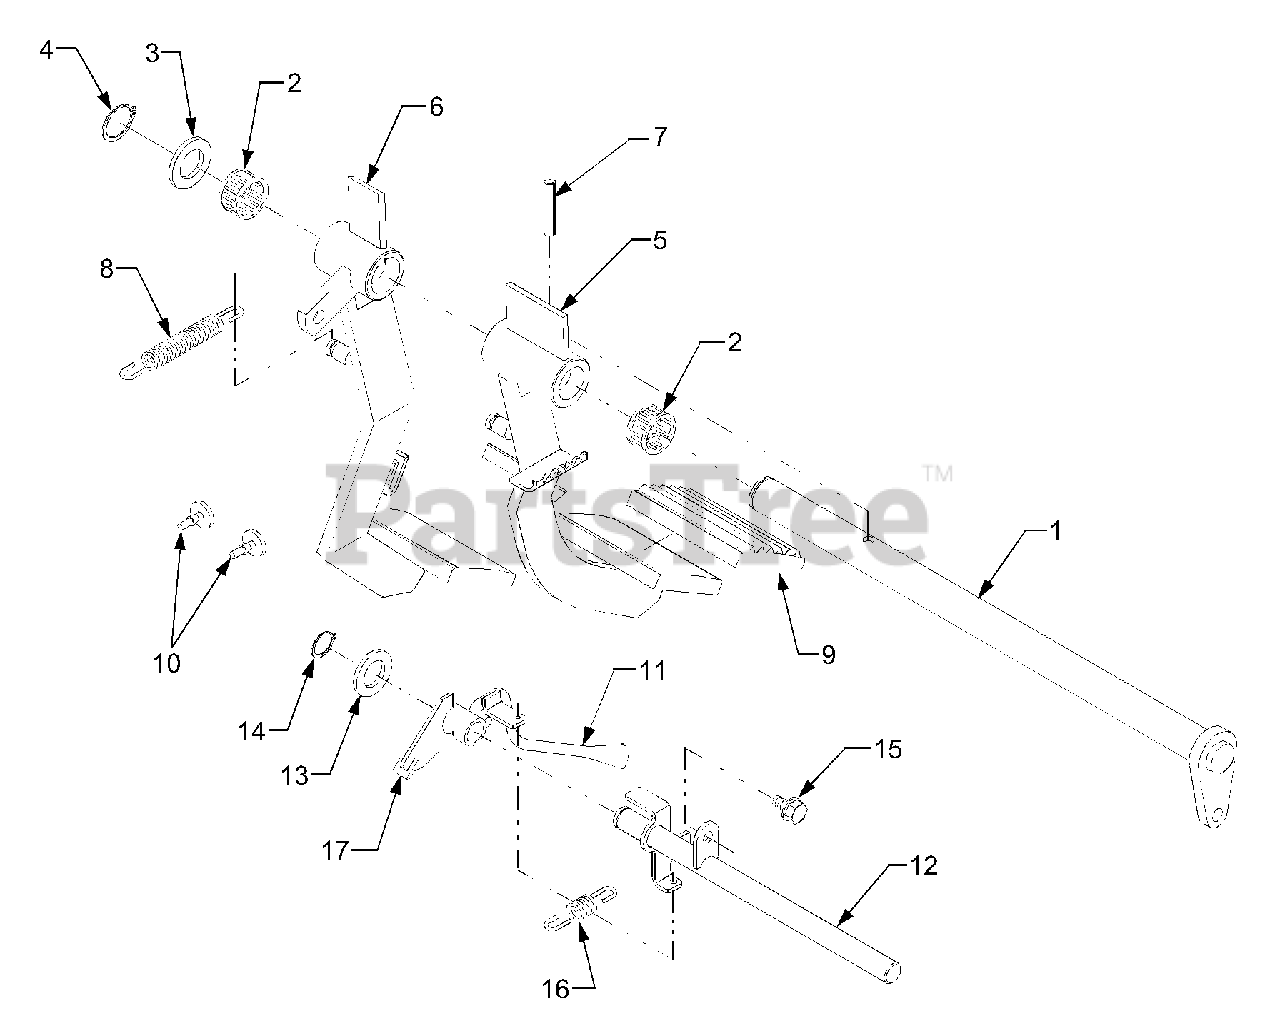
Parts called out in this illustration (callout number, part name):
2	Bearing, Needle
5	Pedal, Brake (LH)
6	Pedal, Brake (RH)
8	Spring, Brake
10	Cushion, Pedal
11	Brake, Parking
12	Shaft, Parking Brake
13	Washer, Plain
16	Spring, Return
